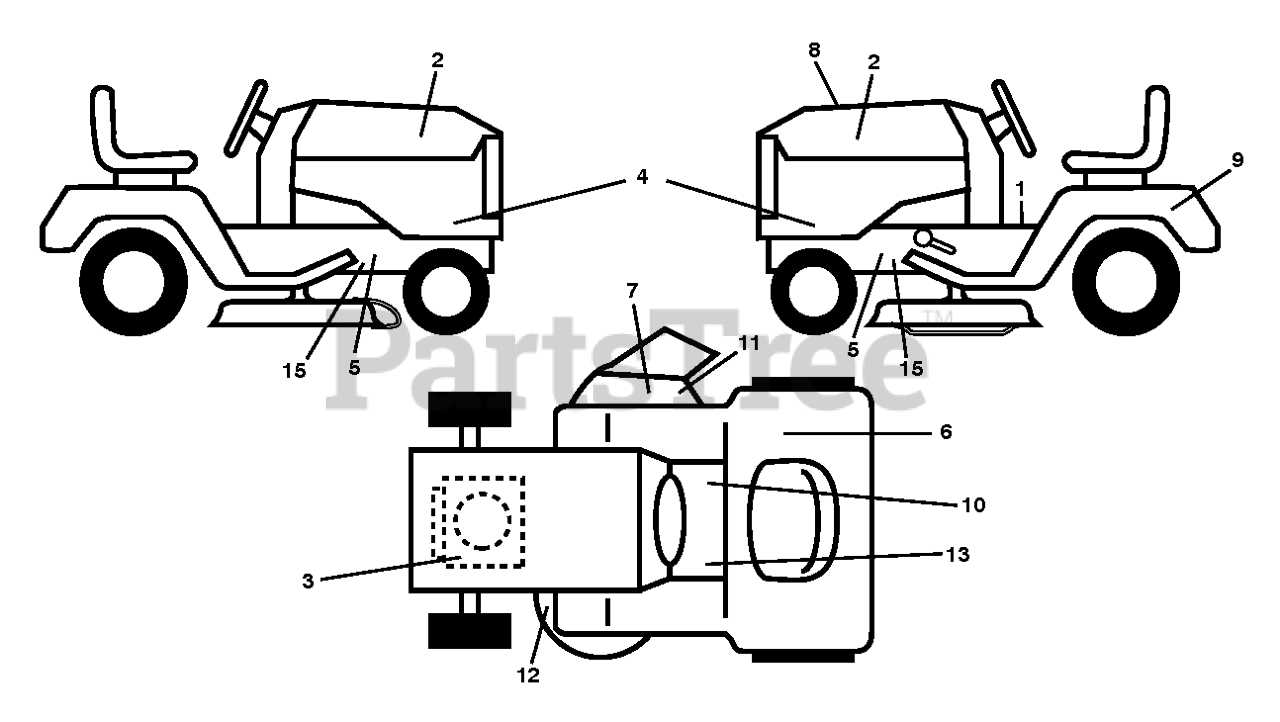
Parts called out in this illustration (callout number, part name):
1	DECAL.READ.OWN.MAN.SYMBOL.LT
2	DECAL.BADGE.170MM.TEXTLOGO.
3	DECAL.ENGINE.WARNING
5	DECAL.CHASSIS.HOT.MUFFLER
6	DECAL.CERTIFICATION.6MIL.100D
7	DECAL.CUTFINGER.CE.02
9	DECAL BTRY SYMBOLS
10	DECAL.PARKING.BRAKE.SADDLE.LT
11	DECAL.DFLCTR.WARNNG.CTFNGR.SYM
12	DECAL.DECK.SCH.36,38,94.NONCR
13	DECAL.FNDR.SDLE.BRAKE.CLUTCH.6
15	DECAL.WARNING.SERVCE/FIRE
